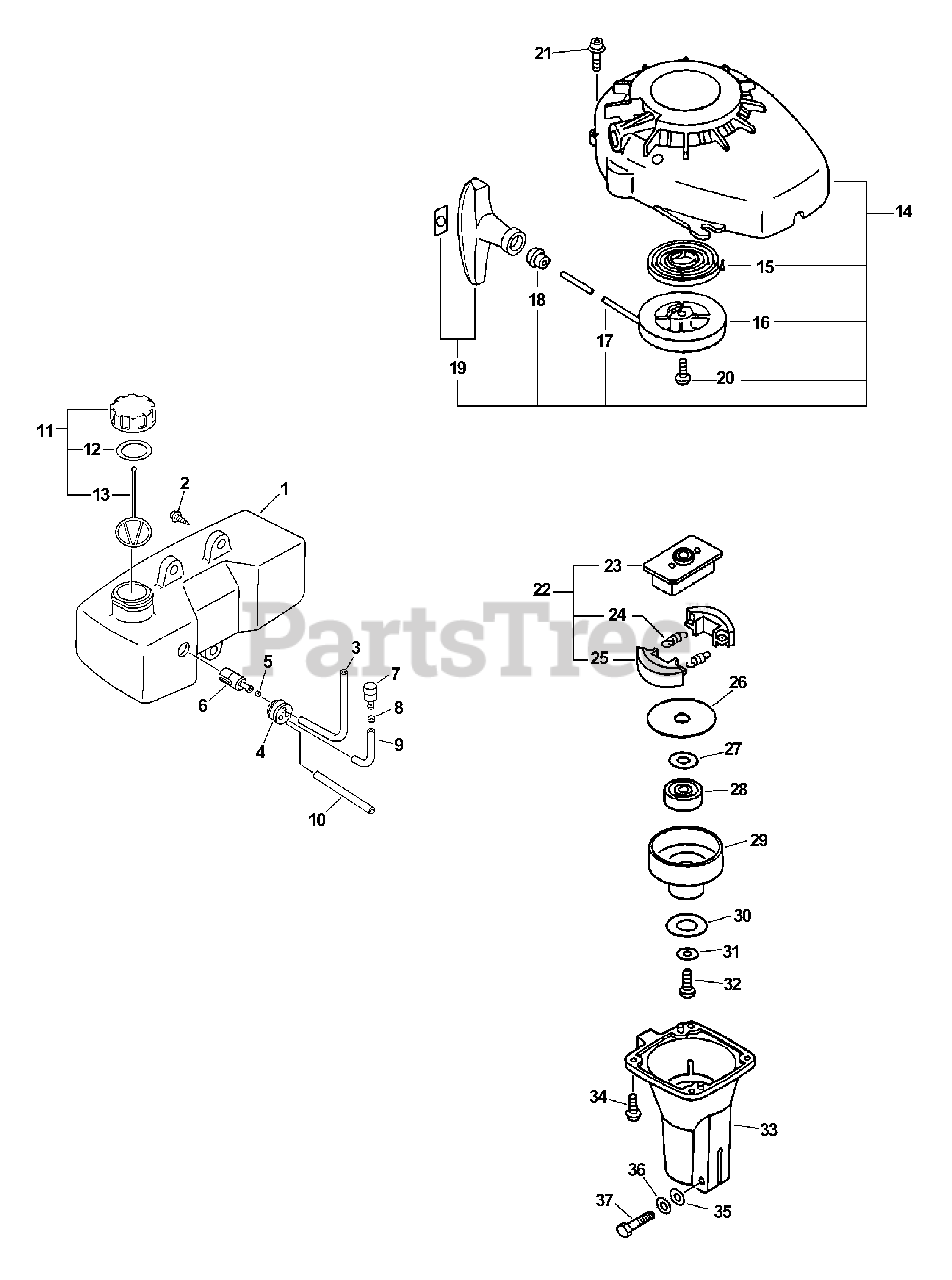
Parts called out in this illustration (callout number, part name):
1	TANK, FUEL
2	SCREW 5×15
3	PIPE, FUEL 3×5×210 BLACK
4	GROMMET, FUEL
5	CLIP 6 MM
6	FILTER, FUEL
7	VENT ASSY
9	PIPE, FUEL 3x-5x-70 BLACK
10	PIPE, FUEL 3×6×50
11	CAP ASSY
12	GASKET, FUEL CAP
13	CONNECTOR, CAP L= 100 MM
14	STARTER ASSY
15	SPRING, RECOIL
16	REEL, ROPE
17	ROPE, STARTER
18	GUIDE, ROPE
19	GRIP, STARTER
20	SCREW
21	SCREW 4×16
22	CLUTCH ASSY
23	HUB, CLUTCH
24	SPRING, CLUTCH
25	SHOE, CLUTCH
26	PLATE, CLUTCH
27	WASHER 10.5×18×1.6
28	BEARING, BALL 6000-2RLB
29	DRUM, CLUTCH
31	WASHER, CLUTCH
32	SCREW 6×12
33	CASE, CLUTCH
34	SCREW 4×14
35	WASHER, FLAT 5.5×10×0.8
36	WASHER, SPRING 5
37	BOLT 5
